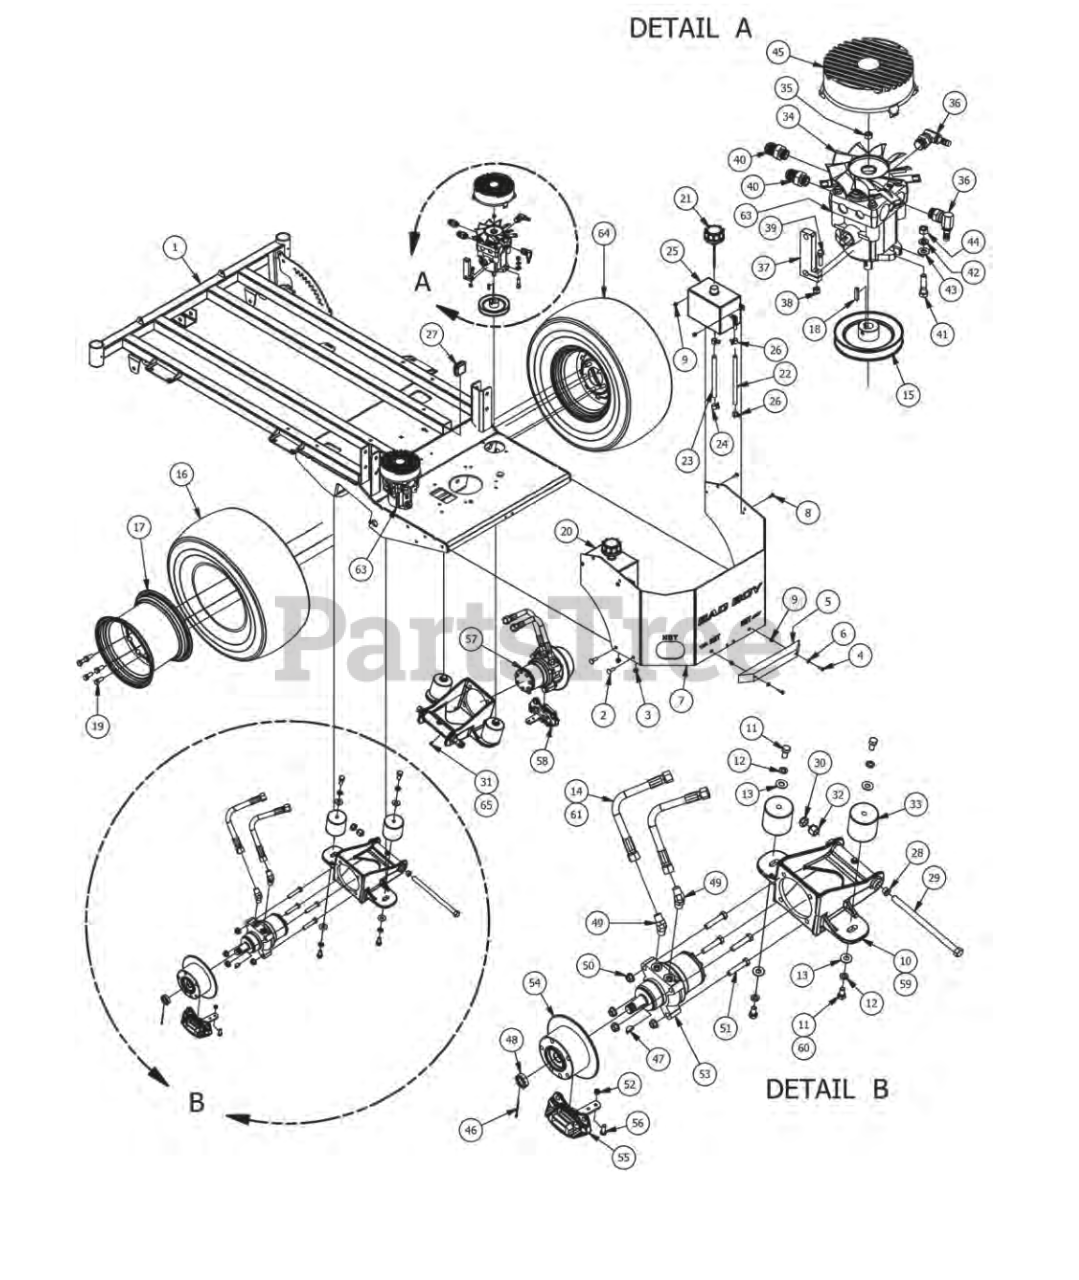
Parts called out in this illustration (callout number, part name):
1	2015 XP Frame
2	3/8" x 1 1/4" Carriage Bolt
3	3/8 Nylock Nut
4	1/4-20 x 1-1/4 GR 5 Hex Bolt
5	14" Rubber Bumper
6	1/4" Flat Washer
7	2015 Outlaw Rear Plate
8	1/4" x 3/4" Carriage Bolt
9	1/4-20 Nylon Insert flange Nut
10	60 Suspension kit Wheel Motor
11	1/2" x 1" Hex Bolt
12	1/2" Lock Washer
13	1/2" Washer (Grade 8)
14	18" hose Assembly W/forged 45 Degr
15	5" Pump Pulley
16	24 x 12.00-10 outlaw Tire
17	10" Black Wheel For Outlaw
18	3/16 x 1 Square Key
19	1/2-20 x 1-1/2 Lug Bolts Zinc
20	Outlaw Hydraulic Tank Left
21	Hydraulic Tank Cap W/Dipstick
22	3/8 clear hose
23	1/2 Clear Braded Hose Priced/Foot
24	1/2 Hose Clamp
25	Outlaw Hydraulic Tank Right
26	3/8 hose clamp
27	2X2 Frame Plug
28	Flange Bushing for Deck Arm-Upper
29	5/8x10" Hex Bolt (Grade8)
30	5/8" Nylock (1/2 Jam)
31	1/4" Drive in Grease Fitting (72" Suspension Kit Wheel Moter)
32	5/8 Std NC Nylock Nut
33	Vibration Mount-Green Dot
34	Hydraulic Fan
36	3/8" X 9/16"-18 ORB Male Fitting (S,A-2 P-4)
38	1/4" Nylock Nut
39	1/4-20 x 1 GR 5 hex bolt zinc
40	Hydraulic Pump Fitting 6400-10
41	3/8" x 1 1/2" Hex Bolt
42	3/8" Lock Washer
43	3/8" Flat Washer
44	3/8" Hex Nut
45	Fan Guard 6" Fits wheel Motor Pumps
46	1/8x2-1/4 cotter pin Zinc
47	Woodruff Key
48	1" Castle Nut for Wheel Motor
49	45 Degree Fitting 31704-10-10
50	1/2" Flange Nut
51	1/2" x 2 1/2" Hex Bolt
52	5/16-18 Nylock Insert Locknut
53	15cc Parker Wheel Motor-Left
54	Brake Disk
55	XP/AOS Left Brake Caliper
56	3/8" x 1" Hex Bolt
57	15cc Parker Wheel Motor- Right
58	XP/AOS Right Brake Caliper
59	72" Suspension Kit Wheel Moter
60	1/2-13 x 1 1/4 Hex Bolt (Only on 60" Suspension Kit Wheel Motor)
61	18" Hydraulic Hose Only
62	Right Pump 12cc
63	Left Pump 12cc
64	24 x 12.00-10 Tire and Black Wheel Assembly
65	3/8" Threaded Grease Fitting (60" Suspension Kit Wheel Moter)
